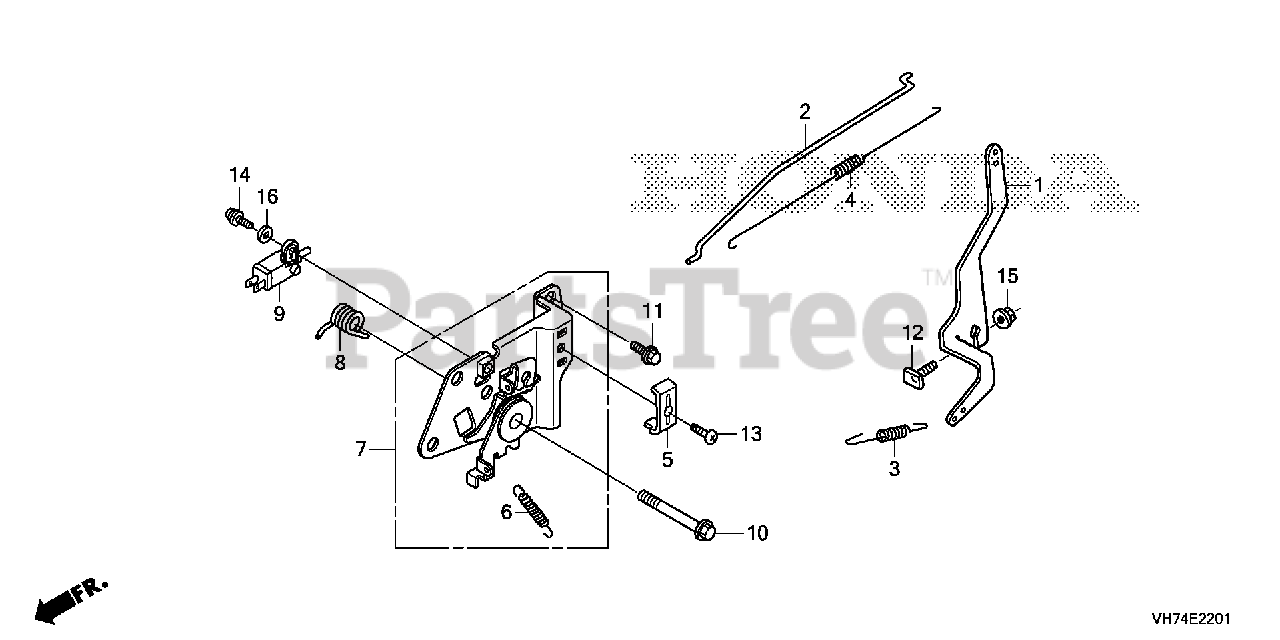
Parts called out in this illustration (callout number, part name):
1	ARM, GOVERNOR
2	ROD, GOVERNOR
3	SPRING, GOVERNOR
4	SPRING, THROTTLE RETURN
5	HOLDER, CABLE
6	SPRING, LEVER
7	BASE, CONTROL
8	SPRING, CONTROL LEVER RETURN
9	SWITCH ASSY., ENGINE STOP
10	BOLT, FLANGE (6X50)
11	BOLT, FLANGE (6X14)
12	BOLT, GOVERNOR ARM
13	SCREW, PAN (5X16)
14	SCREW-WASHER (4X12)
15	NUT, FLANGE (6MM)
16	WASHER, PLAIN (4MM)
